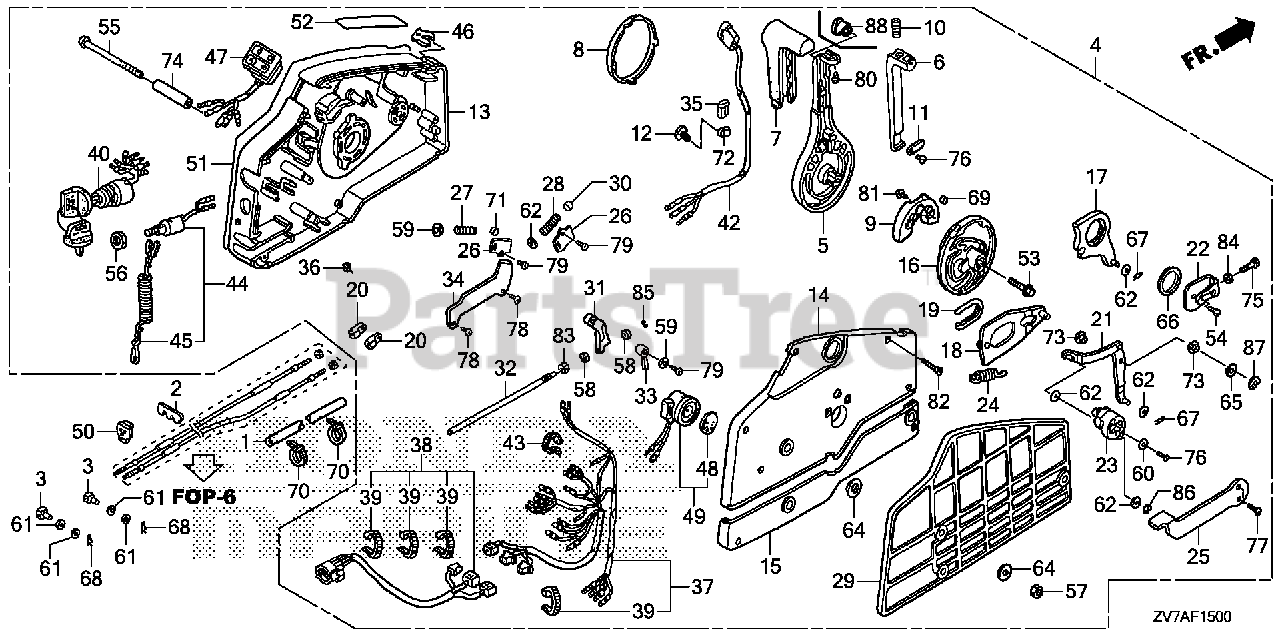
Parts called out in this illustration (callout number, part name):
1	TUBE, CORRUGATE (28MM)
2	PLATE, REMOTE CONTROL CABLE
3	PIVOT, SHIFT
4	S/R SW 2 LIGH MAN TL
4	BOX ASSY., REMOTE CONTROL (A/T)(HI-LEX)
5	HANDLE, REMOTE CONTROL
6	LEVER, HANDLE LOCK
7	GRIP, REMOTE CONTROL HANDLE
8	CAP, HANDLE
9	BLOCK, NEUTRAL LOCK
10	SPRING, REMOTE CONTROL HANDLE
11	PLATE, LEVER SETTING
13	HOUSING, REMOTE CONTROL BOX (A)
14	HOUSING, REMOTE CONTROL BOX (B)
15	HOUSING, REMOTE CONTROL BOX (C)
16	WHEEL, CONTROL
17	ARM, SHIFT LINK
18	PLATE, SLIDING
19	COLLAR, SLIDING PLATE
20	PIVOT, SHIFT
21	ARM, LINK JOINT
22	BRACKET, LINK JOINT
23	WHEEL, ACCELERATOR
24	SPRING, ACCELERATOR WHEEL
25	LEVER, IDLE
26	PLATE, SPRING SETTING
27	SPRING, SHIFT CLICK
28	SPRING, CHOKE RETURN
29	SPACER, REMOTE CONTROL BOX
30	SPACER, CLICK SPRING
31	BLOCK, THROTTLE FRICTION
32	BOLT, FRICTION
33	SPACER, NEUTRAL SWITCH
36	SPACER, CABLE CLAMP
37	CABLE ASSY., REMOTE CONTROL (B)
38	CABLE ASSY., SWITCH PANEL
39	TIE, CABLE (2.4X92) (NATURAL)
40	SWITCH ASSY., COMBINATION
43	BAND (BLACK 3.5X140)
44	SWITCH ASSY., EMERGENCY STOP
45	WIRE, EMERGENCY
46	CLIP, EMERGENCY LOCK
47	LAMP ASSY., INDICATION (2-LED)
48	PLATE, TURN SIGNAL BUZZER
49	BUZZER, WARNING
50	GROMMET, CASE (LOWER) (A)
51	PLATE, REMOTE CONTROL (COUTION COLOR=RED & YELLOW)
52	MARK, FAST IDLE
53	BOLT, FLANGE (8X35)
54	SCREW, PAN (6X10)
55	SCREW (6X95)
56	NUT, HEX. (16MM)
57	NUT, HEX. (6MM)
58	WASHER, PLAIN (4MM)
59	WASHER, PLAIN (5MM)
60	WASHER, PLAIN (5MM)
61	WASHER, PLAIN (6MM)
62	WASHER, PLAIN (6MM)
64	WASHER (6MM)
65	WASHER, PLAIN (8MM)
66	WASHER (28MM)
67	PIN, LOCK (6MM)
68	PIN, SPECIAL LOCK (6MM)
69	PIN (6X6)
70	BAND, SELF-LOCK
71	ROLLER, CLICK
73	COLLAR, LINK JOINT
74	COLLAR, DISTANCE (6X10X43.5)
75	BOLT, HEX. (5X16)
76	SCREW, PAN (5X10)
77	SCREW, FLAT (5X12)
79	SCREW, TAPPING (5X10)
80	SCREW, TAPPING (5X12)
81	SCREW, TAPPING (6X16)
82	SCREW, TAPPING (5X25)
83	NUT, HEX. (6MM)
84	NUT, HEX. (5MM)
85	E-RING (3MM)
86	E-RING (4MM)
87	E-RING (7MM)
88	COVER, GRIP
